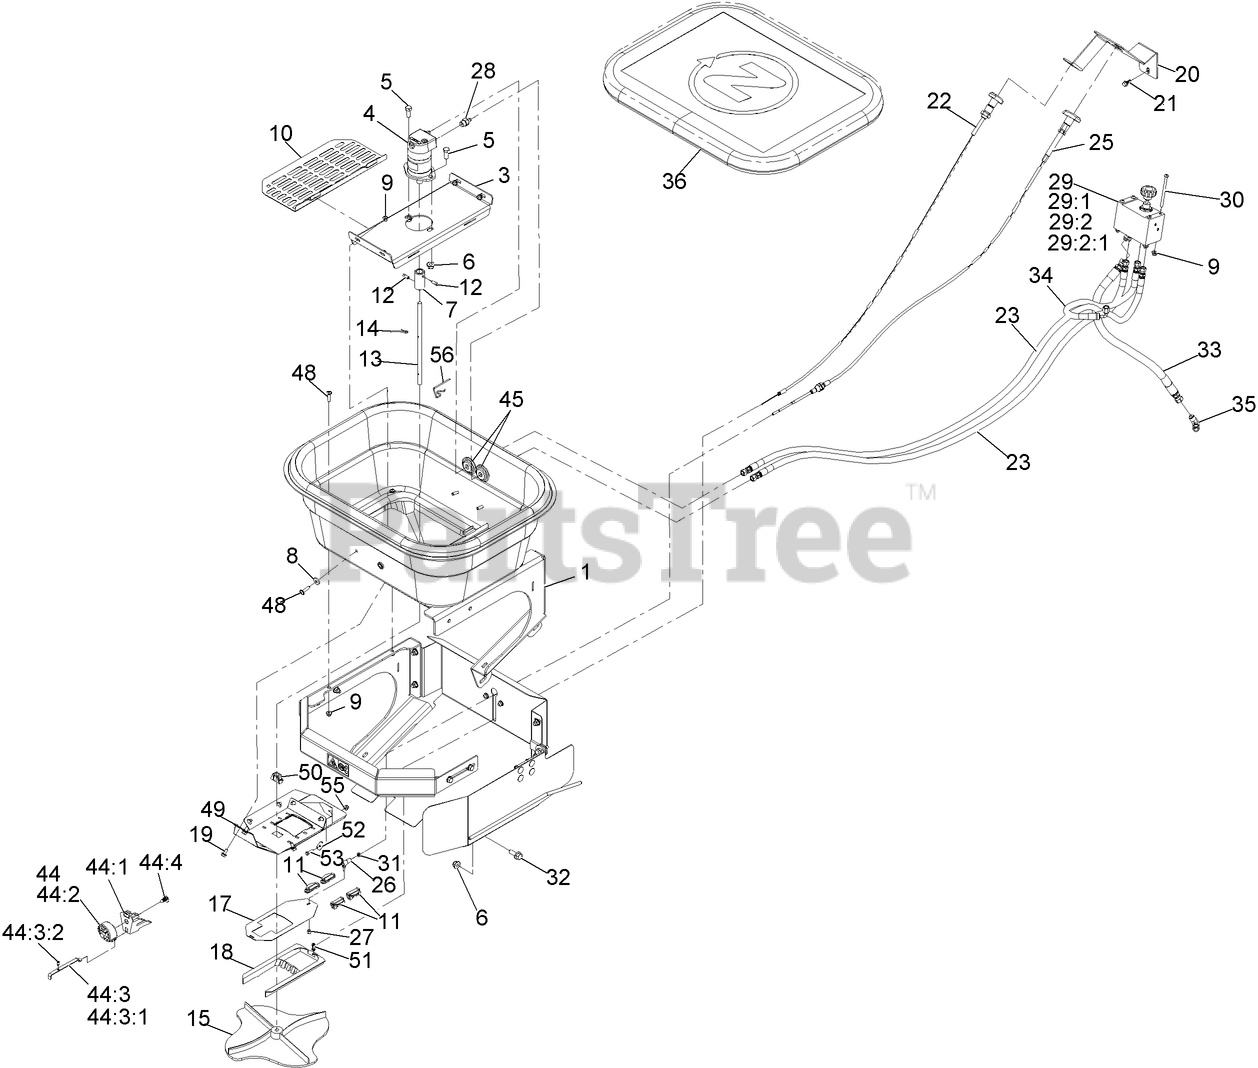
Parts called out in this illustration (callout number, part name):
1	Hopper ASM
3	PAN, HOPPER, 120
4	MOTOR-HYDRAULIC, SPREADER
5	SCREW-HH
6	Nut-Hex Flange
7	COUPLER-SS
9	Nut-Hex Flange
10	SCREEN, HOPPER, 120
11	GUIDE-RATE, GATE
12	Screw-SQH
13	SHAFT-HOPPER, 120
14	WIRE-AGITATOR
15	Spinner-Spreader
17	Slide-Door, Hopper
18	DIFFUSER
19	SCREW-HHF
20	Bracket-Hopper Cable
21	Screw-HHF 1/4-20 X 5/8
22	CABLE-PUSH/PULL
23	HOSE ASM-HYD HP
25	CABLE-PUSH/PULL
26	BALL JOINT-SS
27	Nut,NYL Lock,#10-32,ST/ST 18-8
29	Manifold-Flow Control, Hopper
29:2	FITTING-ELBOW, 45 DEG
29:2:1	O-RING
30	Screw-HSBH
31	Nut,Hex Jam Mch Scr,10-32,Sst
32	SCREW-HHF
33	HOSE ASM-HYD HP
34	HOSE ASM
35	FITTING-90 SWIVEL
36	COVER-HOPPER, SMALL
44	RATE DIAL ASM
44:1	MOUNT-DIAL
44:3	Rate Gate Link ASM
44:3:1	LINK-GATE, RATE
44:3:2	SCREW-SHOULDER, SLOTTED
44:4	Footpad Fastener
45	Grommet-Hopper
48	Screw-Hsbhf
49	BASE PLATE, HOPPER, 120
50	HOPPER BOTTOM BEARING
51	WIRE-STOP
52	RETAINER, CABLE
53	SCREW-HH
55	Nut-Hex Flange
56	Clip-Spinner
